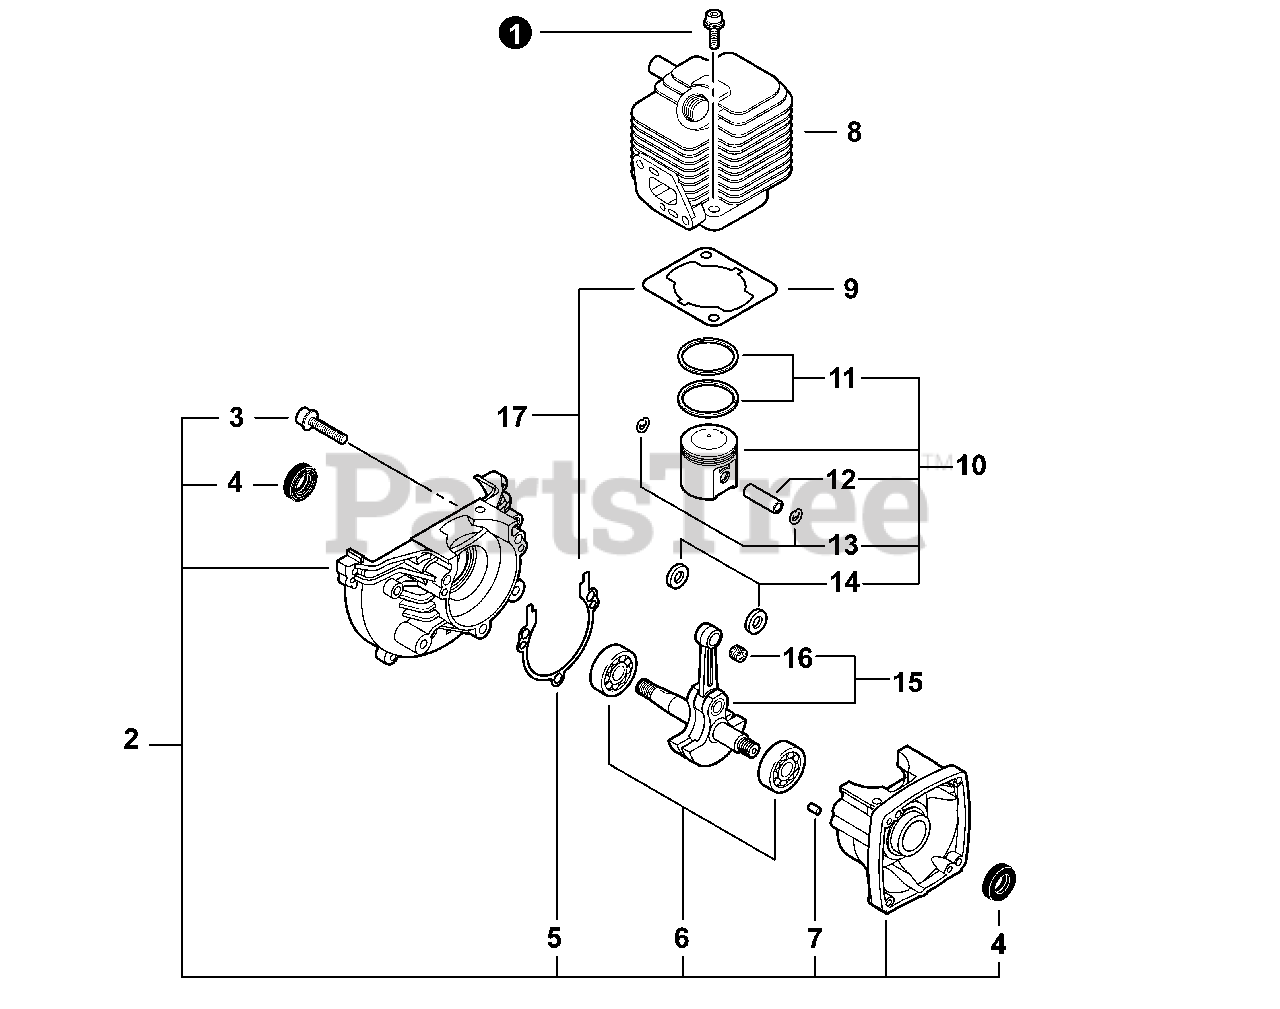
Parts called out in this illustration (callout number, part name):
1	BOLT 5×22
2	CRANKCASE KIT
3	BOLT 5×28
4	SEAL, OIL 12
5	GASKET, CRANKCASE
6	BEARING, BALL 6201
7	PIN, LOCATING 4×8
8	CYLINDER
9	GASKET, CYLINDER
10	PISTON KIT
11	RING, PISTON
12	PIN, PISTON 8
13	RING, SNAP
14	WASHER, THRUST
15	CRANKSHAFT ASSY
16	BEARING, NEEDLE 8
17	GASKET KIT
